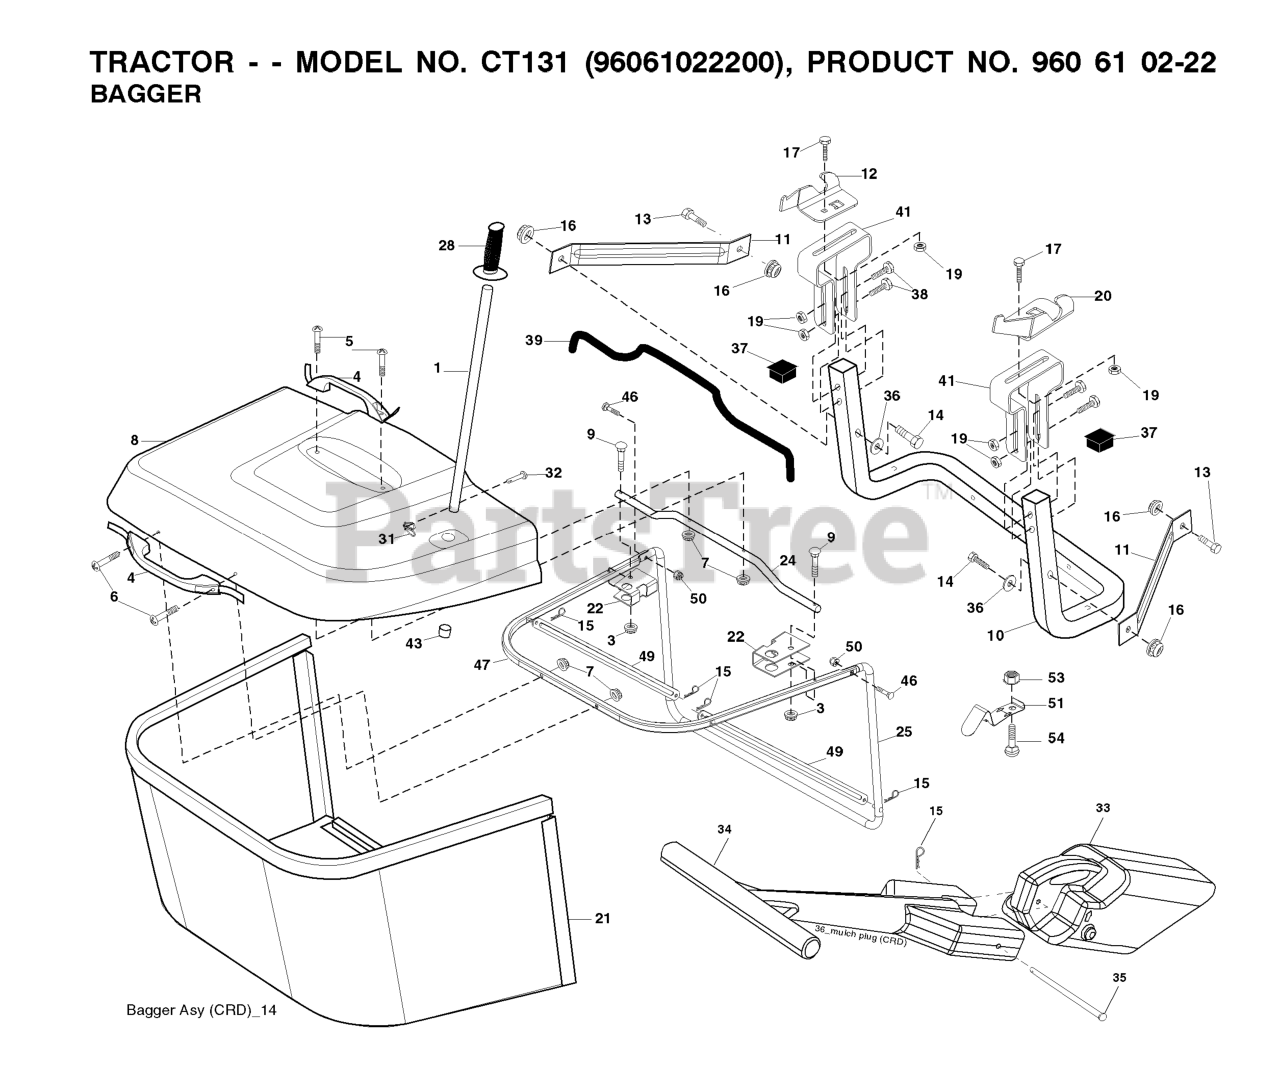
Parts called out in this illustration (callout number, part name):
1	TUBE HANDLE
3	NUT T
4	HANDLE.BAGGER.W/LVRS.BLK.CRD
5	SCREW.PAN.HEAD
6	REPL BY 532 75 00-29
8	COVER.PNT.BGR.CRD.WSLOTS.MS668
9	Bolt Carriage 1/4-20 x 2.25d x Gr.5
10	TUBE
11	BRACKET.SUPPORT.UPPER.BAG.CRD
12	BRKT PIVOT
14	BOLT-HEX EAK
15	RETAINER-SPRNG RB
16	NUT LOCK FLG 3/8-16 UNC
17	RP BOLT 5/16-18 X3/4 ZN/YEL GR
19	NUT LOCK HEX FLANGE 5/16-18
20	BRKT.PIVOT.RH.CRD
21	BAGGER.ASM.CRD.2007
22	BRKT.SIDE.BAG.CRD
24	TUBE.PIVOT.BAG.CRD.BLACK
25	PIPE
28	GRIP.HANDLE.BLACK
31	RETAINER CLIP
32	RIVET,DRILLED
33	PLUG.MULCHER.92 CRD
34	HANDLE.MULCHER.92.CRD (2 2)
36	WASHER
37	Plug Support Bagger CRD
38	BOLT.5/16-18X2.5
39	SEAL.BAGGER.CRD
41	BRKT.VERT.ADJ.BAGGER.CRD
43	PLUG, TUBING END
46	BOLT.CARRIAGE.5/16-18
47	PIPE
49	ROD
50	NUT.71038.31-18.HEX.NYLOCK
51	LATCH
53	NUT
54	BOLT
